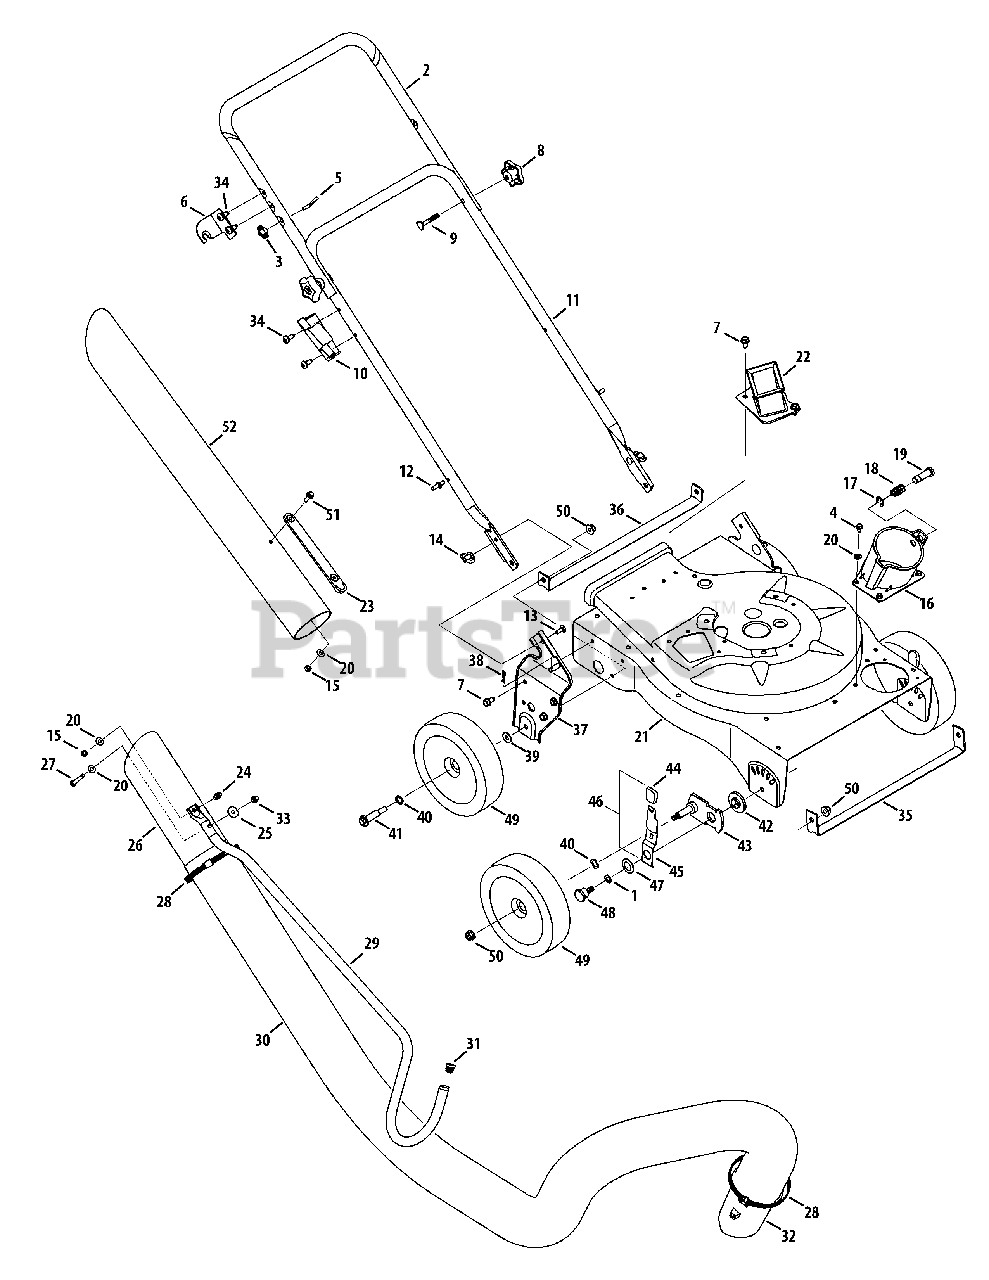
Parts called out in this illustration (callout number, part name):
1	Thrust Washer.375 ID x.70 OD
4	Screw, 1/4-20 x.500
6	Upper Handle Bracket
7	Hex Cap Screw 5/16-12 x.750
9	Carriage Bolt
10	Nozzle Handle Clip
13	Carriage Screw 1/4-20 x.75
14	Wing Nut 1/4-20
15	Hex Lock Nut, 1/4-20
16	Hose Base Adapter Assembly (Incl. Ref.# 17-19)
17	E Ring.500 Dia
18	Compression Spring
19	Clevis Pin
20	Flat Washer.271 ID x.630 OD
21	Upper Flail Housing
22	Chipper Chute Assembly
23	Chute Strap
26	Hose Nozzle
27	Hex Cap Screw 1/4-20 x 2.625
28	Adjustment Clamp
30	Vacuum Hose
31	Handle Plug
32	Hose Adapter
33	Cap Lock Nut, 1/4-20
34	TT Screw, 5/16-18 x .750
35	Front Wheel Support Brace
36	Rear Wheel Support Brace
37	Handle Bracket Ass’y RH
37	Handle Bracket Ass’y LH
38	Cotter Pin
39	Bell Washer.401 ID x.870 OD
40	Wave Washer.531 ID x.781 OD
41	Shoulder Screw 3/8-16
42	Height Adjustment Bearing
43	Pivot Arm Assembly
44	Height Adjustment Knob
45	Spring Lever
46	Height Lever Assembly (Incl. Ref.# 44-45)
47	Bell Washer.760 ID x.25 OD
48	Shoulder Screw,.750 x.500
49	Wheel 8 x 2
50	Flange Lock Nut, 3/8-16
51	Screw, 1/4-20 x .75
52	Hose Extension
